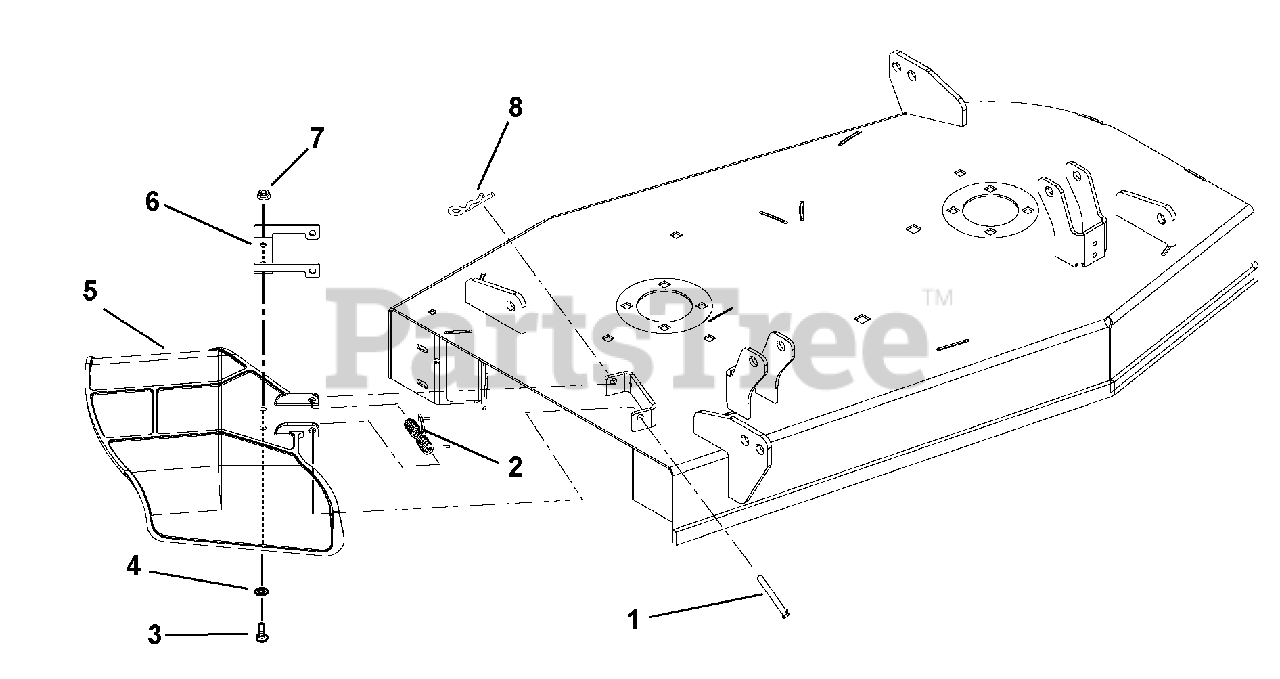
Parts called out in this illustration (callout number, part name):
1	Pin, 5/16 x 3.88"
2	Spring, Torsion
3	Screw, Socket Head, Button Head .31-18 x .75
4	Washer, Flat Steel .38 x .875 x .083
5	Molded Chute
6	Chute Reinforcement
7	Nut, Locking, Top Flange .31-18
8	Pin, Hair .08 x .18 x 1.18
